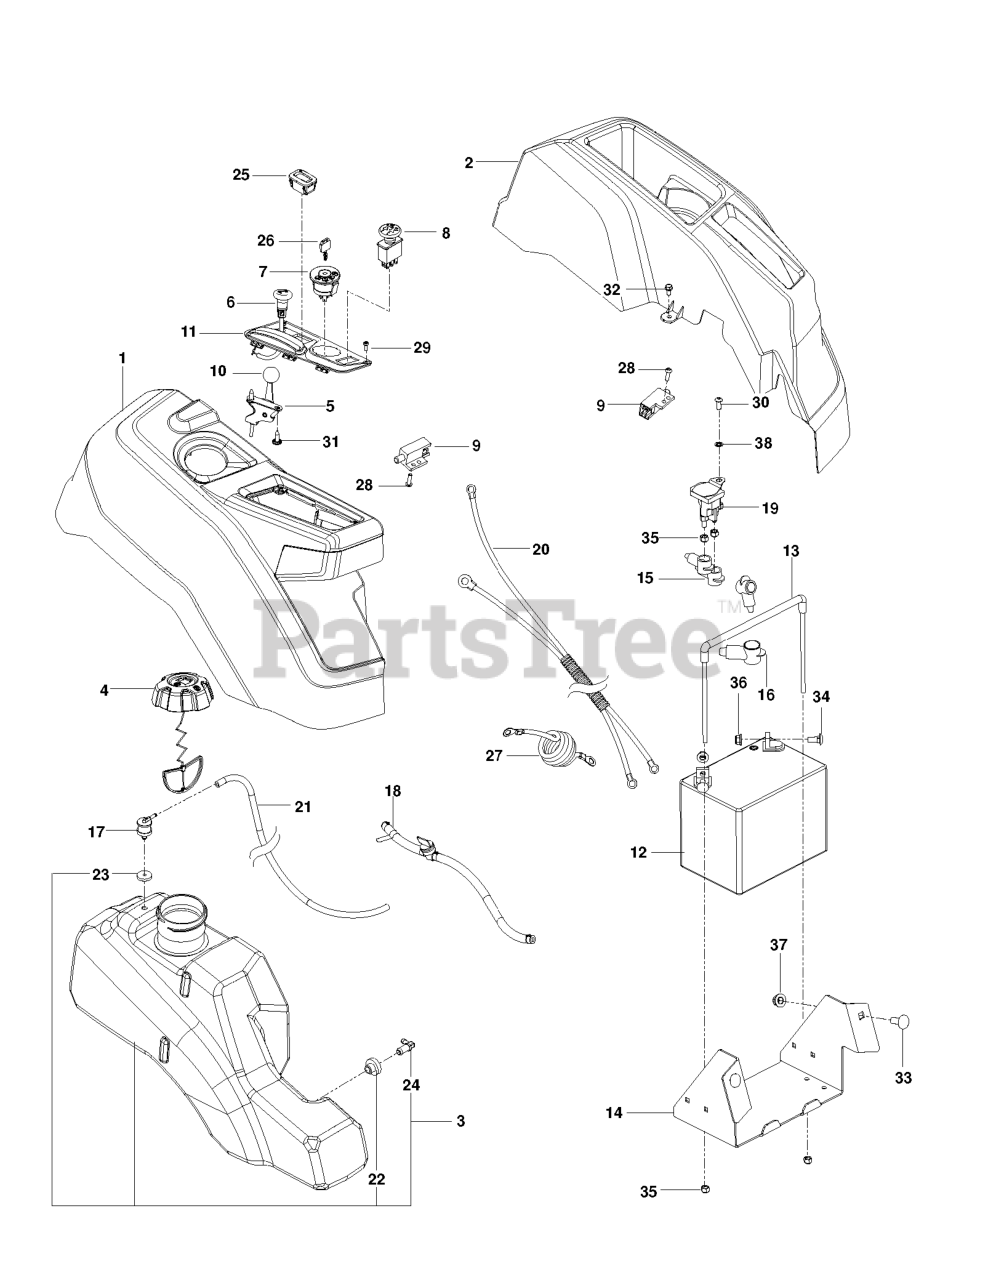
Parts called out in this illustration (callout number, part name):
1	CONSOLE.ASSY.RZ.REFRESH.RH
2	CONSOLE.LH.ASM
3	ASM.FUEL.TANK.LG.3".W/O SHIELD
4	FUEL CAP
4	CAP ASSY FUEL 3" GRAY
5	THROTTLE CABLE
6	CHOKE.PUSH-IN.STYLE
7	RP IGNITION SWITCH
8	RP.PTO.SWITCH.8 TERMINAL.BLACK
9	SWITCH.INTLK.RZ.RFRSH.BUTTON
10	KNOB.ROUND.BALL.BLACK
11	CONTROL.PANEL.RZ.REFRESH.RH
12	BATTERY, 12 V 300 AMP DRY
13	BATTERY TIE DOWN ASSEMBLY
14	BOX BATTERY RZ BLACK
15	COVER.TERMINAL.RED
17	VALVE.FUEL.CHECK
18	FUEL.HOSE.SHUT.OFF.ASM.10".3"
19	SOLENOID.W/BRASS.PLUNGER
20	HARNESS.BTTRY.CABLE.RZ.REFRESH
21	HOSE.3/16".VAPOR.LINE.23"LGTH
22	BUSHING OUTLET T
23	GROMMET.ROV.SENTEC
24	STEM FUEL TANK
25	GUAGE.SRVCMNDR.HRMTR.
26	KEY MLD GEN DELTA
27	CABLE POSITIVE, LONG
28	SCR #10-24 X .75 SKT HD BLK
29	SCREW
30	SCR 1/4-20 X 5/8 BTN SKT HD ZD
31	SCREW.PAN.HEAD.#10
32	HCS 1/4-20.
33	RHSNB 3/8C X 1
34	RP BOLT 5/16-18 X3/4 ZN/YEL GR
35	NUT.CROWNLOCK.1/4
36	5/16-18 NYLOC FLANGE NUT
37	NUT 3/8-16 HEX FLG NYLOC ZD
38	WASHER 1/4 INT TOOTH
